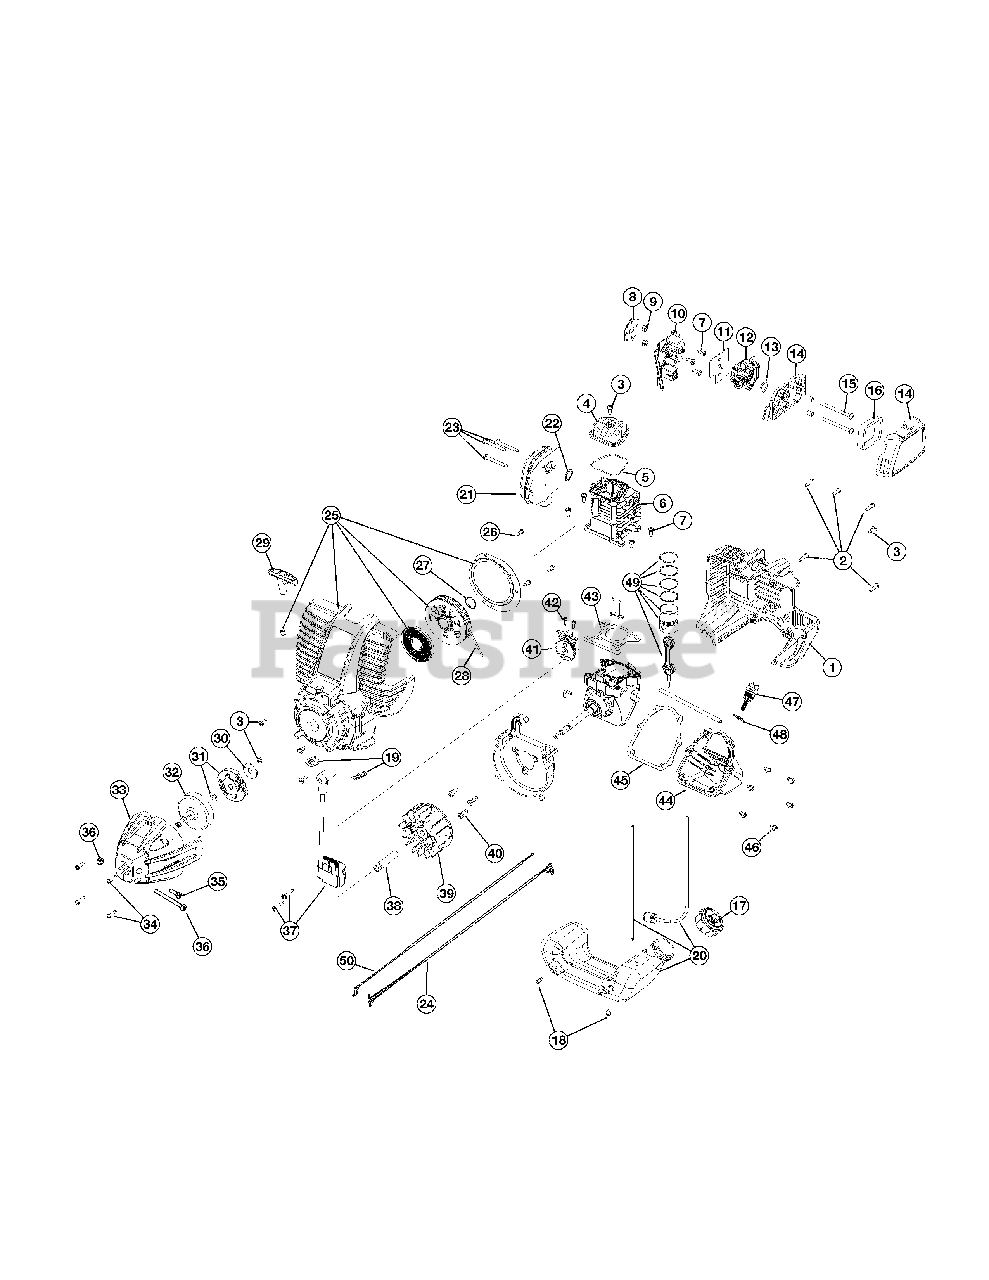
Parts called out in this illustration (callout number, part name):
1	Engine Cover
4	Valve Cover
5	Valve Cover Gasket
6	Cylinder Assembly (includes 5, 7 & 43)
7	Cylinder Screw
8	Insulator Gasket
10	Insulator (includes 11)
11	Carburetor Gasket
12	Carburetor w/Primer
13	Carburetor O-Ring
14	Air Filter Cover Assembly (includes 16)
15	Air Filter Mounting Screw
16	Air Filter
17	Fuel Cap
19	Clip Nut
20	Fuel Tank Assembly (includes 17)
21	Muffler Assembly (includes 22 & 23)
22	Muffler Gasket
23	Muffler Mounting Screw
24	Lead Wire
25	Starter Housing Assembly (includes 3 & 26-29)
26	Plate Screw
27	Push Nut
28	Rope
29	Pull Handle
30	Washer
31	Clutch Assembly
32	Clutch Drum
33	Clutch Cover Assembly (includes 34-36)
34	Cover Screw
35	Anti-Rotation Screw
36	Clamping Screw Assembly
37	Ignition Module Assembly
38	Spacer
39	Flywheel
40	Shroud Screw
41	Cam Bracket Assembly (includes 42)
42	Cam Bracket Screw
43	Cylinder Gasket
44	Oil Pan (includes 45 & 46)
45	Oil Pan Gasket
46	Oil Pan Screw
47	Dipstick Assembly (includes 48)
49	Piston Assembly
50	Throttle Cable
